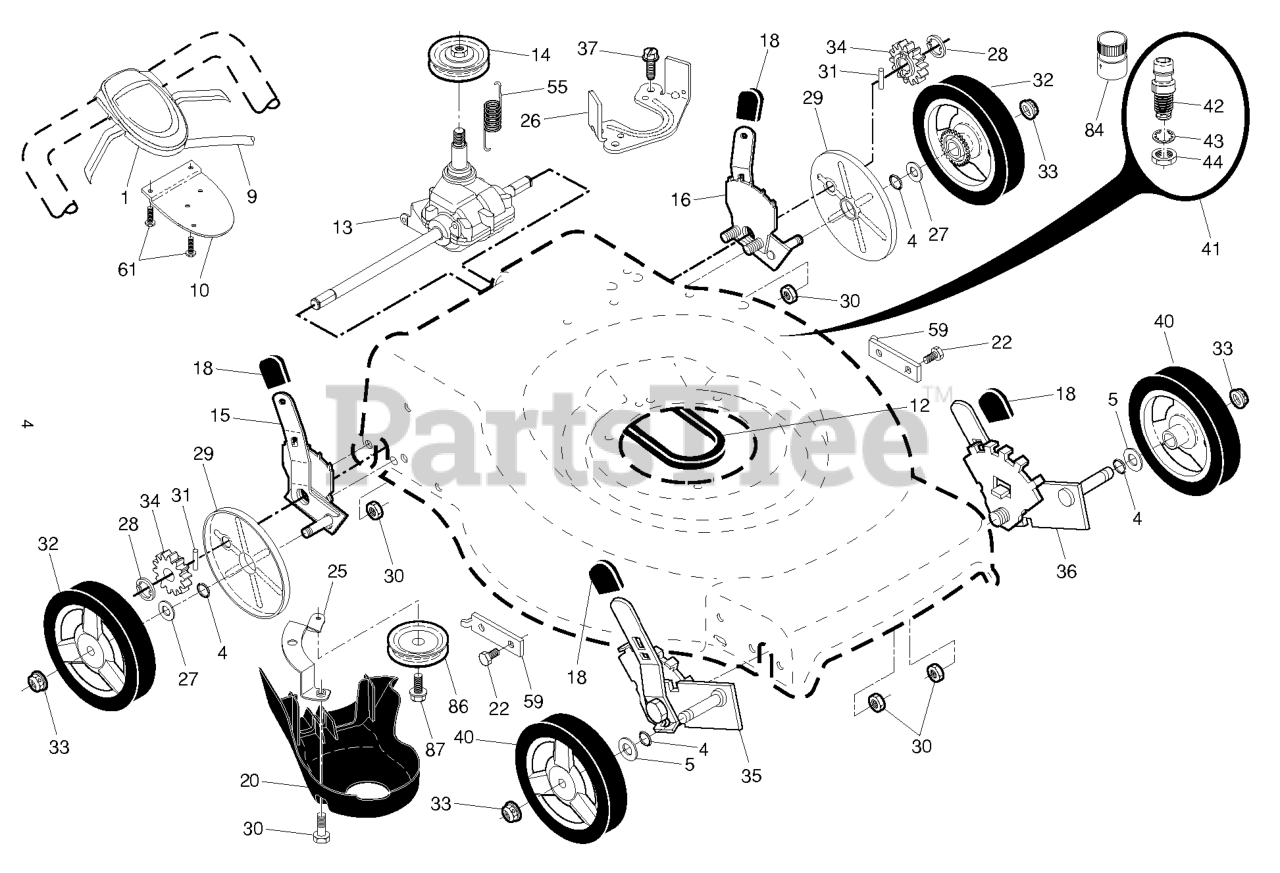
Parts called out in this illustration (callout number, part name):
1	RB CONTRL.AW2.22+RGD.BS.GRY/BK
4	O-RING..070X.487.NEOPRENE
5	WASHER.FLAT.1/2
9	CABLE.CONTROL.22RGD.GEN2
10	BRACKET.DRIVE.CONTR.GEN2.BLACK
12	RP.BELT.DRIVE.RGD.SS.WALK
13	TRANSMISSION.22+AWD.WALK.MOWER
15	RP_ADJUSTER.ASM.AWD.RT.ZINC
16	RP_ADJUSTER.ASM.AWD.LT.ZINC
18	SELECTOR KNOB
20	COVER.REAR.DRIVE.22+2013
22	BOLT.5/16HEX.WHS.HD
25	BRACKET.DRIVE.COVER.RGD.
26	BRACKET.TRANS.BELT.KEEPER.BZP
27	WASHER FLUT
28	E-RING 7/16 RE
29	COVER.DUST.WHEEL.INNER.WALK
30	NUT.HEX.FLANGE.1/4
31	PAWL, DRIVE
32	WHEEL.8X1.75.3SPK.RAD3.GREY
33	NUT.HEX.FLANGE.3/8-16.LO(3 2)
34	PINIION.14.TOOTH.RGD
35	ADJUSTER.ASM.9POS.LW.RGD.FR
36	ADJUSTER.ASM.LH FRONT/RH REAR
40	WHEEL & TIRES ASSY, FRONT
41	KIT.WASH-OUT.PORT.ZINC.WALK
42	WASHOUT.PORT.ZINC.RGD.22+
43	WASHER.LOCK.INTERNAL.TOOTH
44	LOCKNUT.HEX.WITH.O-RING
55	SPRING.RETURN.AUTO.
59	BRACKET.SUPPORT.22+RWGD.BZP
61	SCREW, PHILLIPS HEAD 10 X 5/8
84	COUPLING.QUICK CONNECT
86	RP PULLEY.AWD.IDLER
